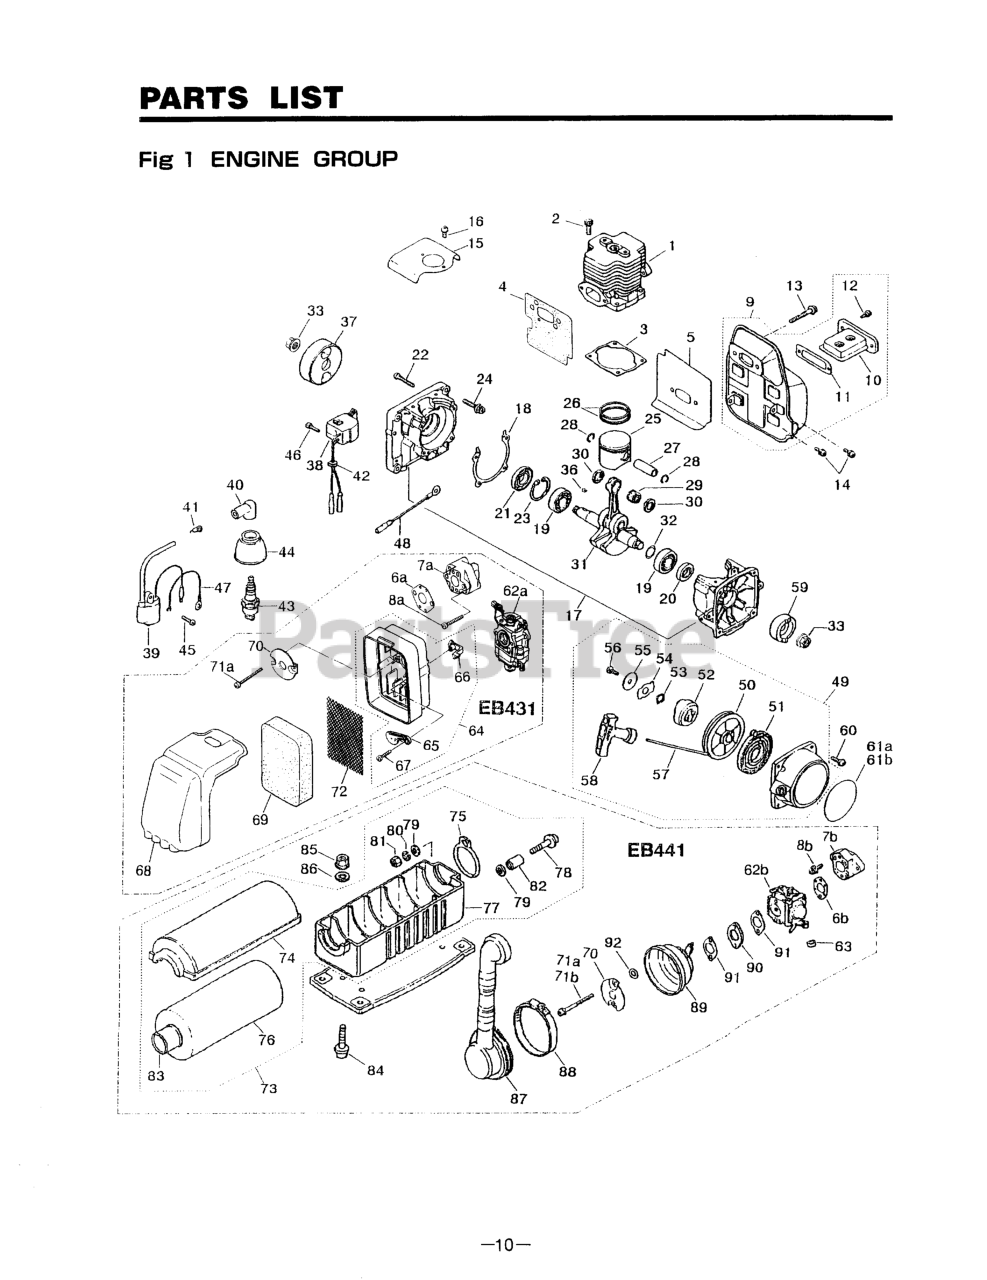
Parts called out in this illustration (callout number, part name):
1	CYLINDER (RPLS -12111)
2	BOLT, M5 x 22
7B	INSULATOR (RPLS-14112)
9	MUFFLER (RPLS -15101)
10	ARRESTER
12	SCREW, M4 x 10
17	CRANKCASE
20	SEAL, OIL - STARTER SIDE
22	BOLT, M5 X 30
23	RING, SNAP, M35 X 1.5
26	RING, PISTON (RPLS -41210)
27	PIN, PISTON (RPLS. 1490-41316)
28	RING, SNAP
29	BEARING
30	WASHER (RPLS 1491-41510)
31	SHAFT (RPLS -42001)
32	SHIM (REPLACES 848-870-G000)
33	NUT, M10
36	KEY
39	COIL, IGNITION
41	SPRING
42	GROMMET
44	CAP (NO LONGER AVAILABLE)
45	SCREW, M4 x 16
46	BOLT, M4 X 16
47	CABLE COMPLETE
51	SPRING (RPLS -75220)
52	DOG
53	WASHER
54	RETAINER (RPLS 1861-75161)
55	WASHER
56	SCREW
57	ROPE
58	KNOB
59	PULLEY (RPLS -75210)
60	BOLT, M5 x 20
63	CAP, CABLE END
70	PLATE (REPLACES -82511)
71B	SCREW, M5 X 55
73	CLEANER, AIR
74	COVER, CLEANER
75	BAND
76	ELEMENT
77	CASE, CLEANER
79	WASHER, M5 X .8
80	WASHER, SPRING M4 x 1.3
81	NUT, M5 X 4
82	COLLAR (NLA)
84	SCREW, M5 x 16
85	NUT (B)
86	WASHER, M5 X .8
87	HOSE (RPLS -83300)
88	CLAMP
89	CASE, CLEANER
NI	KIT, GASKET
